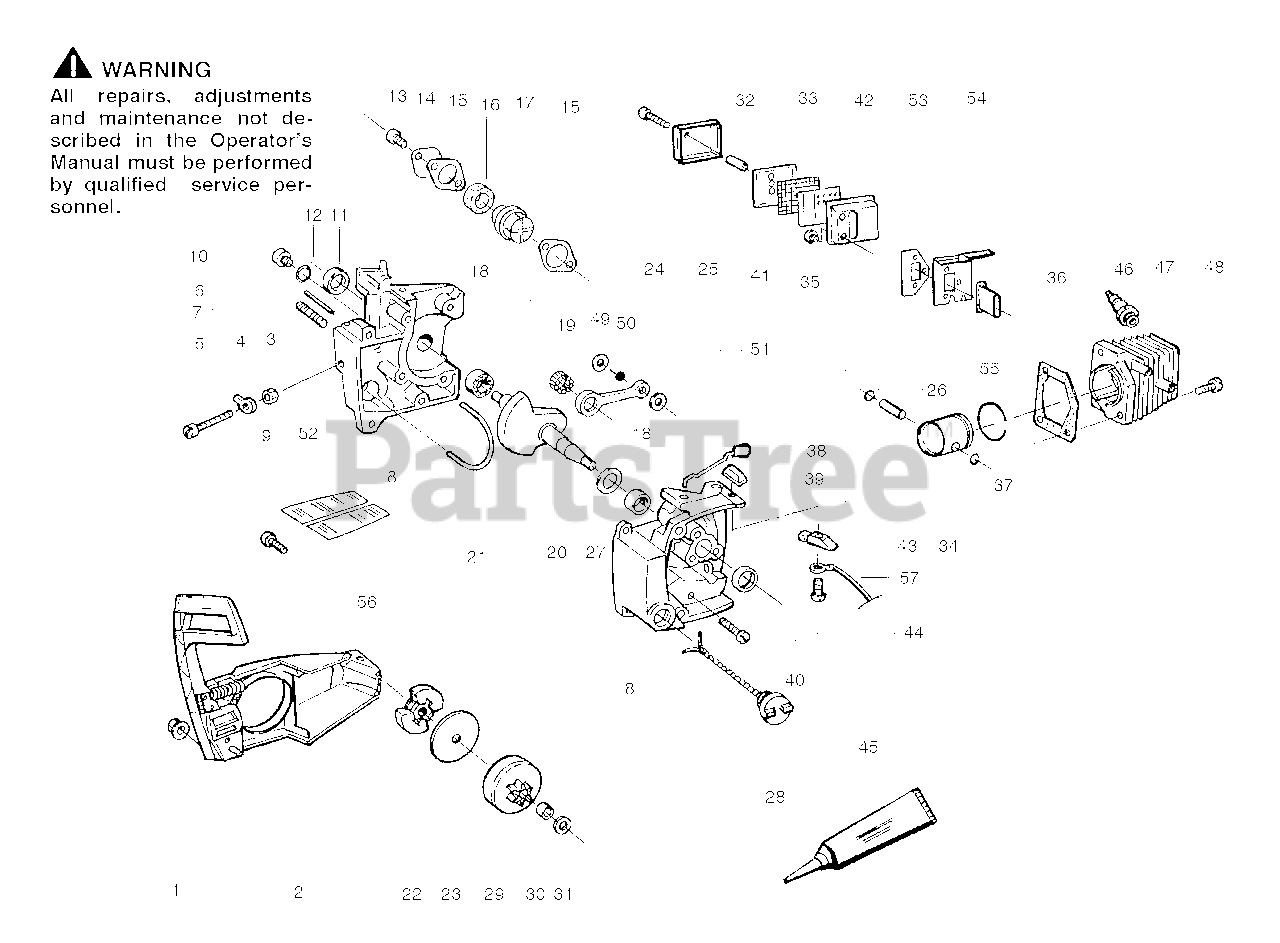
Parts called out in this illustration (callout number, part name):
1	Bar Mounting Nut
2	Chain Brake Ass'y.
3	Locknut
4	Bar Adjust Pin
6	Oil Tank Vent Pin
7	Bar Mounting Stud
8	Kit-Crankcase Ass'y.
10	Check Valve Kit
11	Crankshaft Seal
12	Check Valve Gasket
14	Oil Pump Cover
15	Oil Pump Gasket
16	Oil Filter
17	Oil Pump Body Ass'y.
18	Crankshaft Bearing
19	Roller Bearings
20	Crankshaft
21	Oil Discharge Line
22	Clutch Ass'y. Kit
23	Clutch Washer Kit
25	Muffler Cover
26	Piston Pin Retainer
27	Thrust Washer
28	Oil Cap Ass'y.
29	Clutch Drum & Brg. Kit
30	Clutch Bearing
31	Muffler Spacer
33	Spark Arrestor Screen
34	Piston Kit
36	Cylinder Gasket
37	Piston Ring
38	Knob Switch
39	Ramp Switch
41	Muffler Baffle
42	Muffler Body
43	Switch Clamp Insulator
45	Crankcase Sealant
46	Spark Plug (CJ-7Y)
47	Cylinder
50	Bearing Rod Top
51	Connecting Rod Ass'y. Kit
52	Kickback Decal
53	Gasket-Muffler
54	Muffler-Back Plate
55	Port-Insulator
56	On/Off Decal Warning
57	Switch Lead Wire
